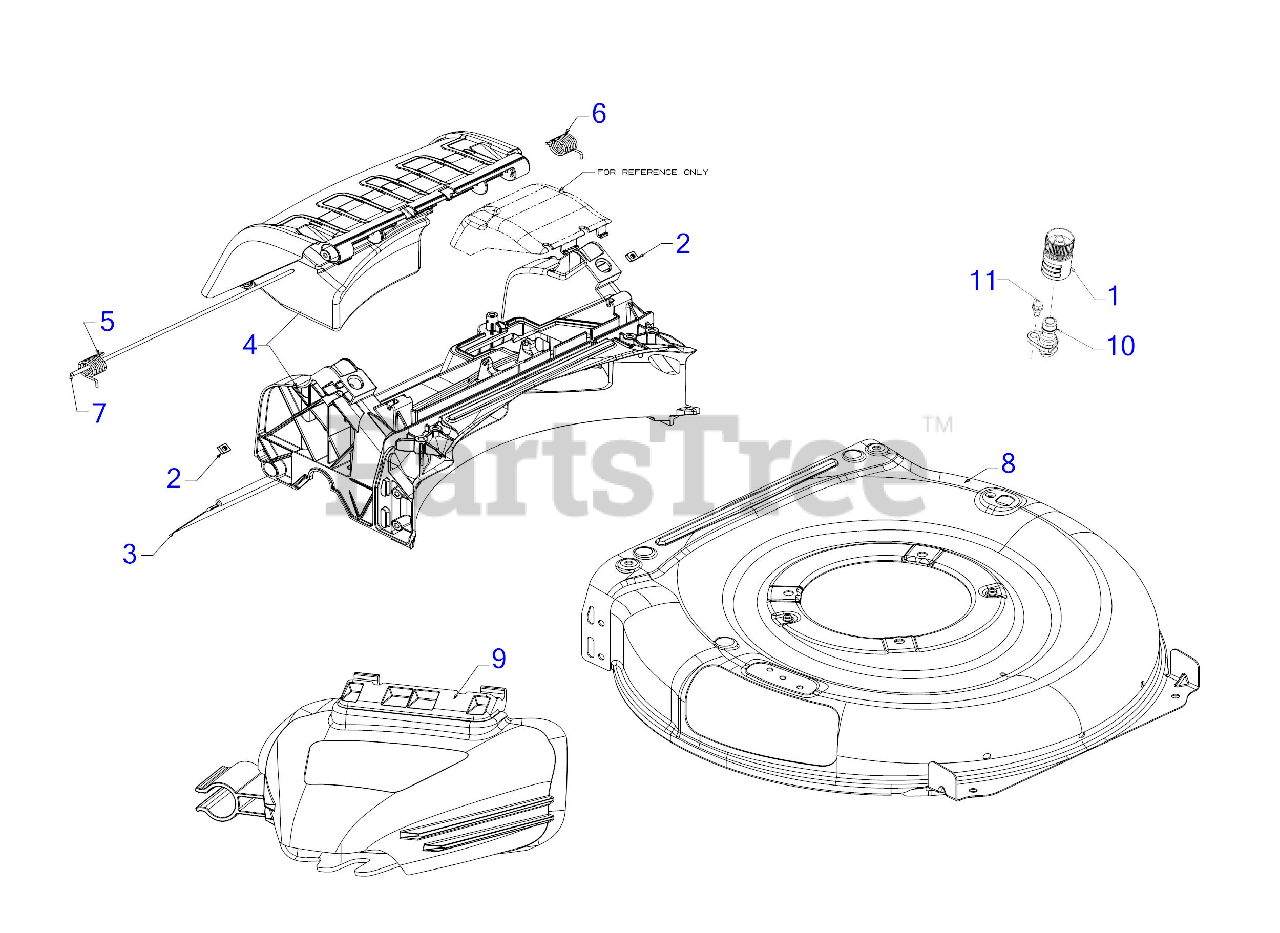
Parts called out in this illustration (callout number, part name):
1	WATER NOZZLE
2	SQUARE NUT 1/4-20
3	TRAILSHIELD
4	REAR BAG BAFFLE ASSEMBLY
5	TORSION SPRING (RH)
6	TORSION SPRING (LH)
7	REAR DOOR PIVOT ROD
8	21" DECK ASSEMBLY
9	MOWER BLOWER CHUTE
10	DECK WASH NOZZLE
11	SHOULDER SCREW 1/4-20 x .50
